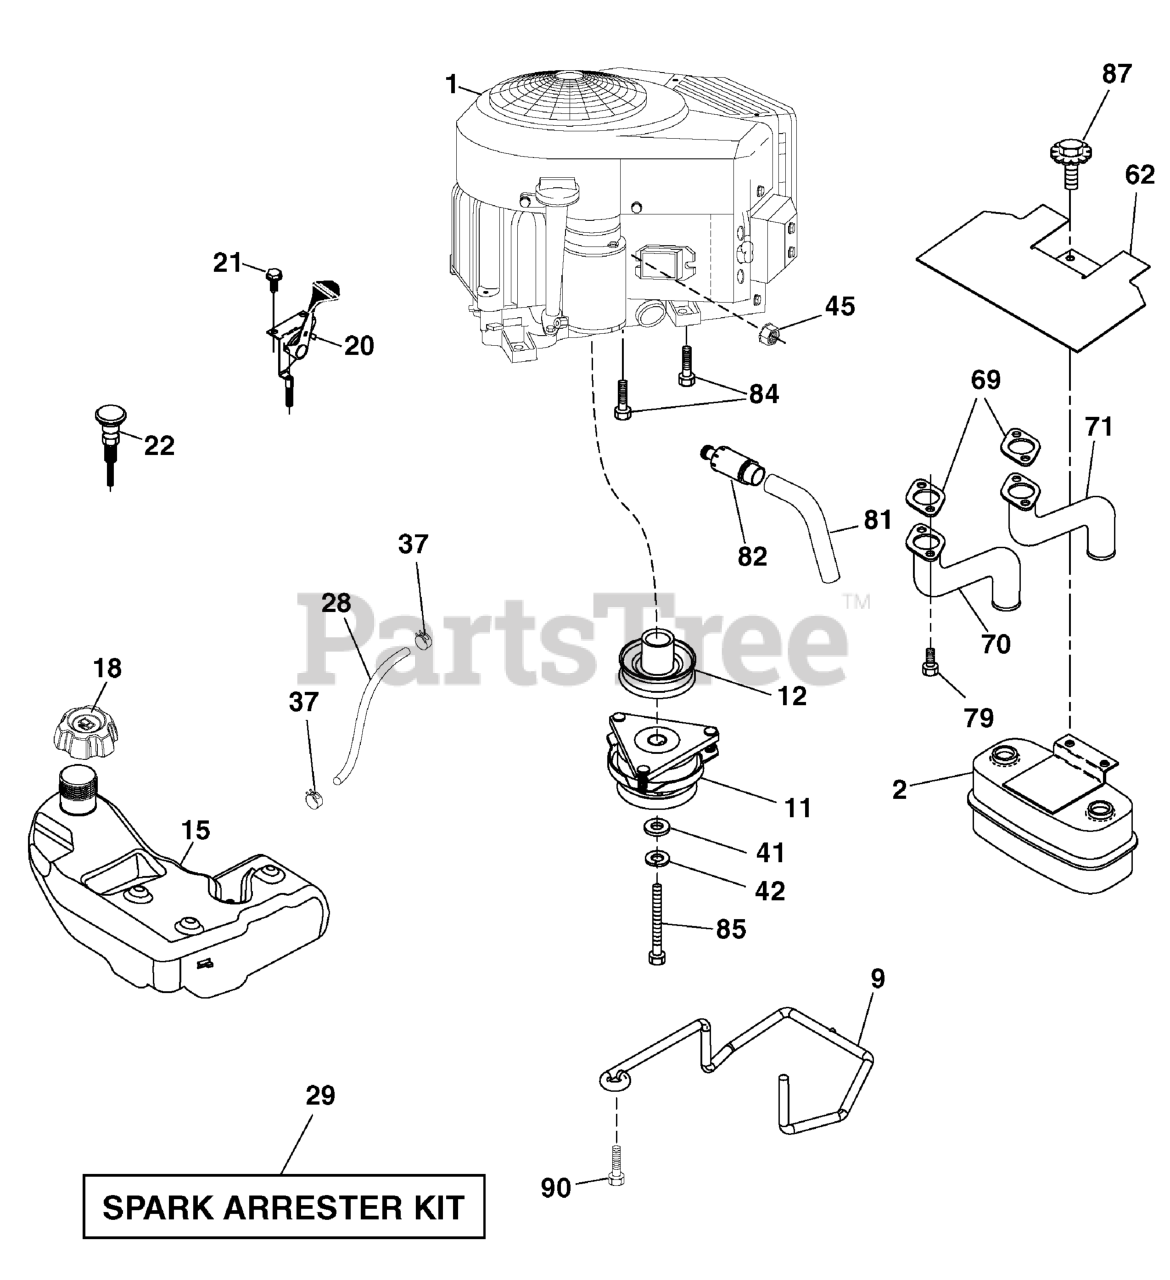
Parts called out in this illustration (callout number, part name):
1	* Engine, Briggs & Stratton
2	Muffler
9	Keeper Asm. Belt Engine
11	Clutch Electric
12	** Pulley Engine
15	Tank Fuel 4.0
18	Cap Asm
20	** Control
21	Screw 10 x .750 BOS Thread
22	Control Choke
28	Fuel Line
29	Spark Arrester Kit
37	Clamp Hose
41	Washer 1-1/2 OD x 15/32 ID x .250
42	Washer Lock 7/16
45	Nut Keps 1/4-20 unc
62	Shield Heat Muffler
69	Gasket
70	** Tube Exhaust LH
71	** Tube Exhaust RH
79	Screw Socket Head 5/16-18 x 1
81	Tube Drain Oil Easy
82	Valve Oil Drain
84	Screw 3/8-16 x 1-1/4
85	Bolt Hex 7/16-20 x 3.75 Gr. 5
87	Bolt 5/16-18 unc x 1 w/Sems
90	Screw 3/8-16 x 1
